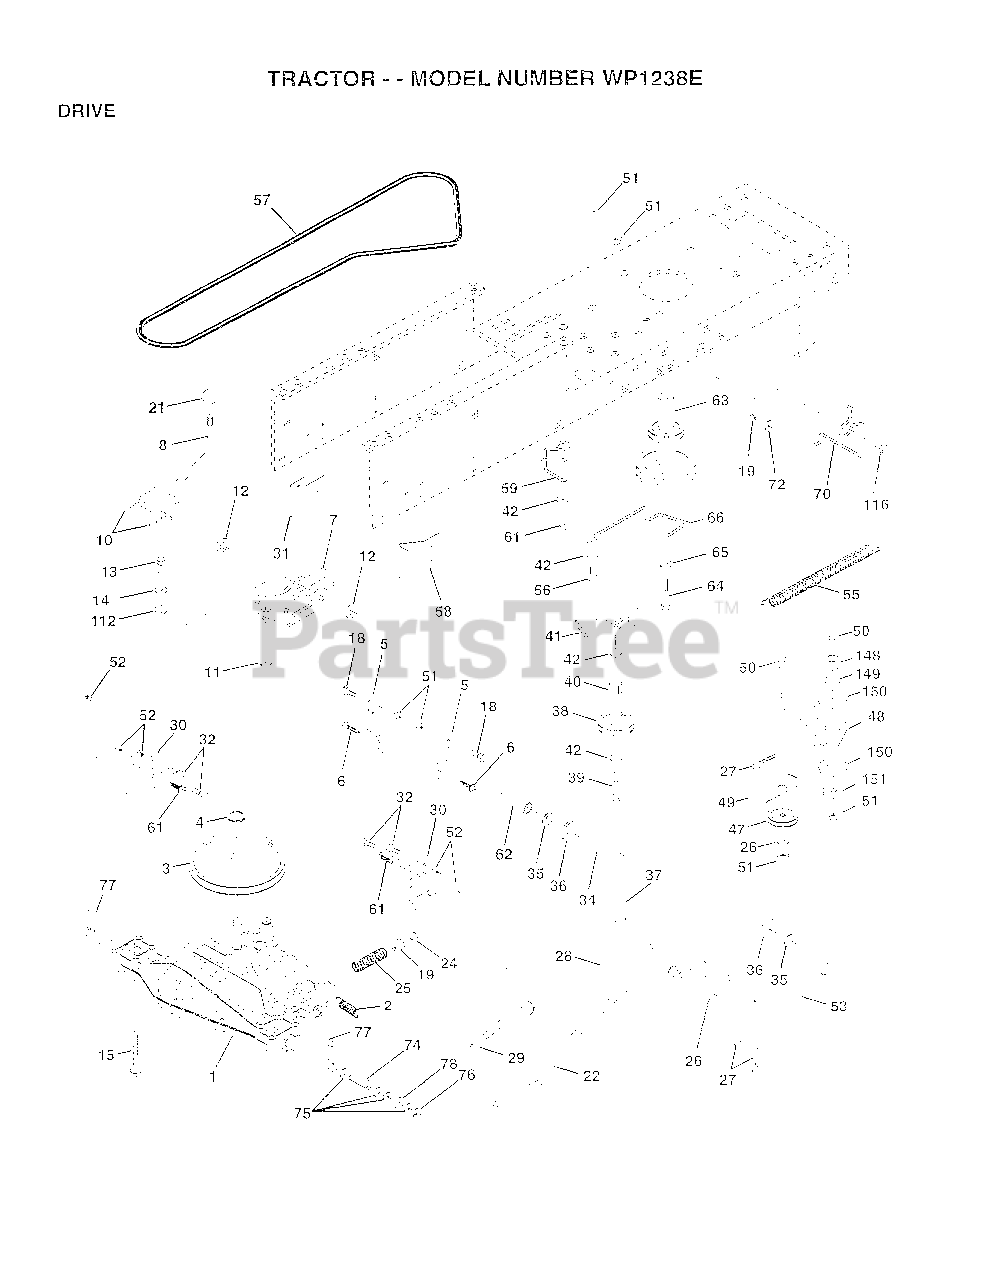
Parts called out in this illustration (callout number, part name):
2	SPRING.BRAKE.RETU
3	PULLEY TRANS
5	STRAP TORQUE
6	SCREW
7	BRKT.SADDLE.SHIFT
8	SHIFT ROD
10	PIN COTTER 1/8
11	WASH-SHFT PLT LT
12	WASHER
13	BOLT.1/4-28.W/PAT
14	LOCKWASHER
15	BOLT.HX.FLG.5/16
18	BOLT
19	NUT
21	KNOB T (1/2-HOLE)
22	BRAKE ROD
24	NUT
25	SPRING ROD LT
26	WASHER
27	COTTER PIN
28	ROD.BRAKE.PARK.LT
29	PLUNGER CAP T
30	TRANSAXLE MTG BKT
31	"KEEPER,BELT LH T"
32	BOLT
34	SHAFT ASM-PEDAL F
35	NYLON BEARING
36	WASHER LT
38	PULLEY.IDLER.FLAT
39	BOLT
40	SPACER T
42	WASHER
48	BELLCRANK.CLUTCH
49	RETAIN BELT
53	"LINK, CLUTCH T"
55	"SPRING, RETURN LT"
58	"KEEPER,BELT RH T"
59	KEEPER BELT CNTSP
61	SCREW
62	PEDAL COVER T
63	PULLEY.ENGINE
64	BOLT
65	LOCKWASHER
66	KEEPER-BELT
72	WASHER
74	SPACER LT
76	E-RING LT
77	SQUARE KEY
78	WASHER
112	WASHER LT
116	BOLT RDHD 3/8-16
149	SPACER RETAINER
150	BUSHING.NYLON
151	WASHER
